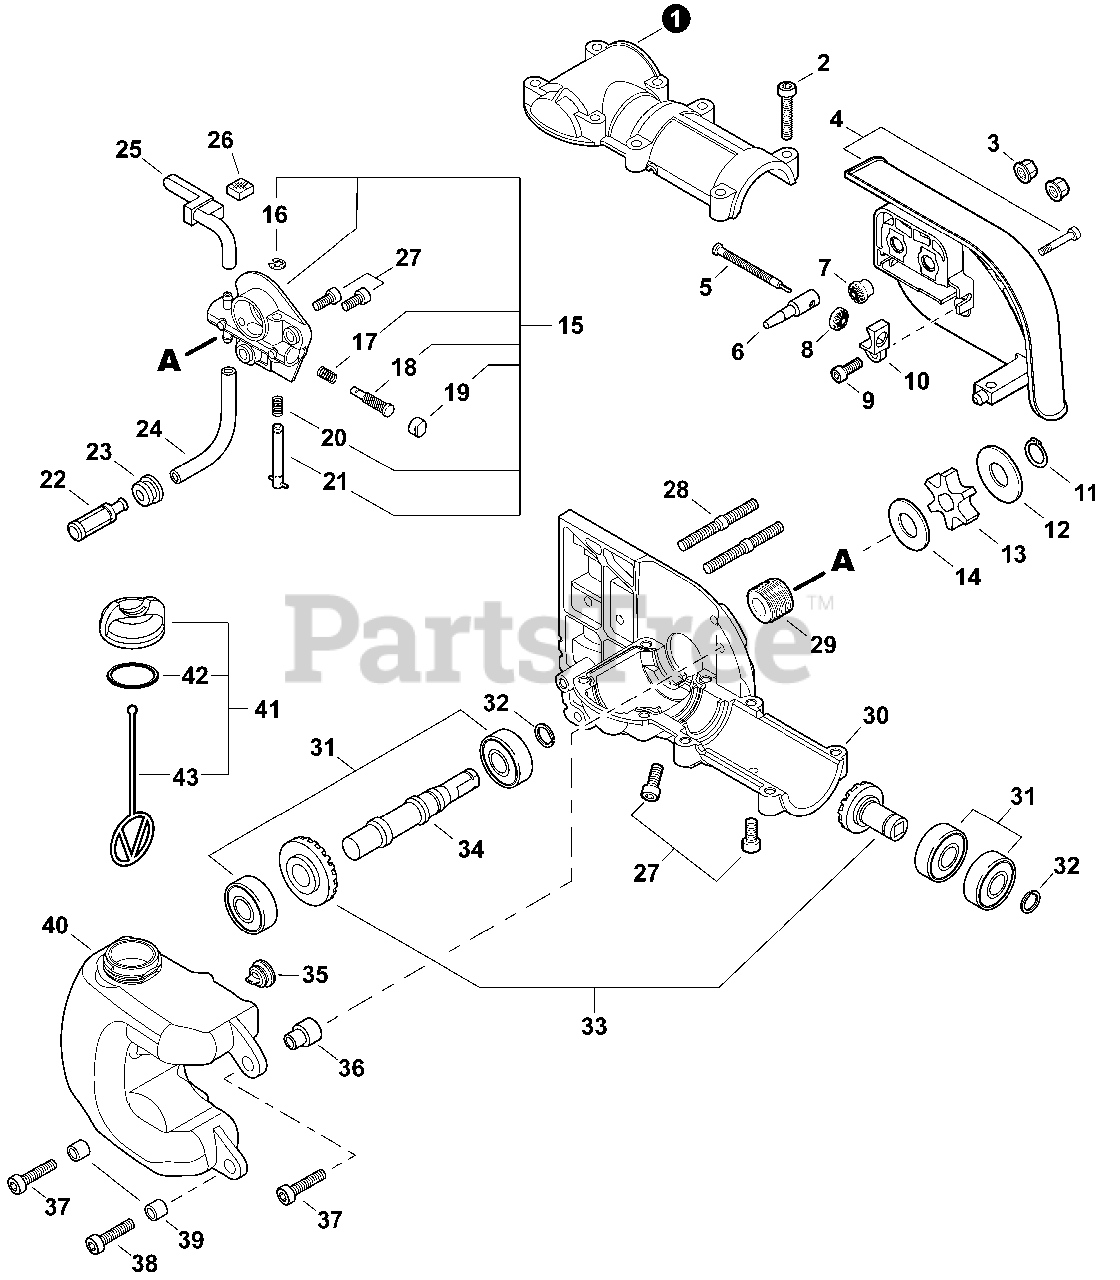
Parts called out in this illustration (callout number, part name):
1	COVER, GEAR CASE
2	BOLT, TORX 5×25
3	NUT, FLANGE M6
4	GUARD, SPROCKET
6	TENSIONER, CHAIN
7	GEAR - 14 TOOTH
8	GEAR - 14 TOOTH
9	SCREW 4
10	COLLAR 8
11	RING, SNAP
12	WASHER 10
13	SPROCKET, DRIVE
14	WASHER 10.2×24.5×1.2
15	AUTO-OILER ASSY
18	PLUNGER ASSY
19	CAP, PLUNGER
21	ADJUSTER, OILER
22	FILTER, OIL
23	GROMMET
24	PIPE 3×6×70
25	PIPE, OIL OUTLET
26	PAD, FOAM
27	BOLT, TORX 5×10
28	BOLT, STUD 6
29	GEAR, WORM
30	CASE, GEAR
31	BEARING, BALL
32	RING, SNAP Ø12
33	GEAR SET
34	SHAFT, GEAR
35	VENT ASSY
36	COLLAR 6
37	BOLT, TORX 5×20
38	BOLT, TORX 5×25
39	SPACER 6.2×7.8×6
40	TANK, OIL
41	CAP ASSY
42	O-RING 18
43	CONNECTOR, CAP L= 60 MM
